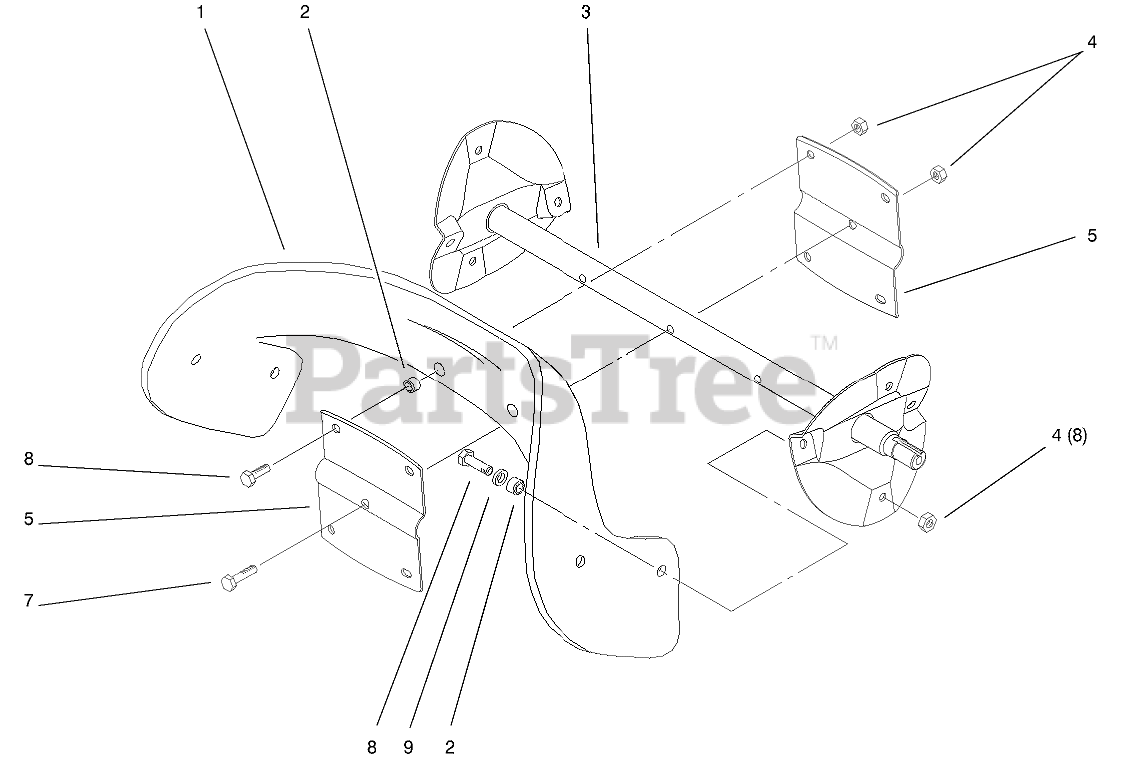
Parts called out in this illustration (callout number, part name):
1	BLADE-ROTOR
2	SPACER-BLADE, ROTOR
3	Rotor
4	NUT-LOCK, NI
5	HALF-ROTOR
7	SCREW-HH
8	SCREW-HH
9	WASHER-FLAT
